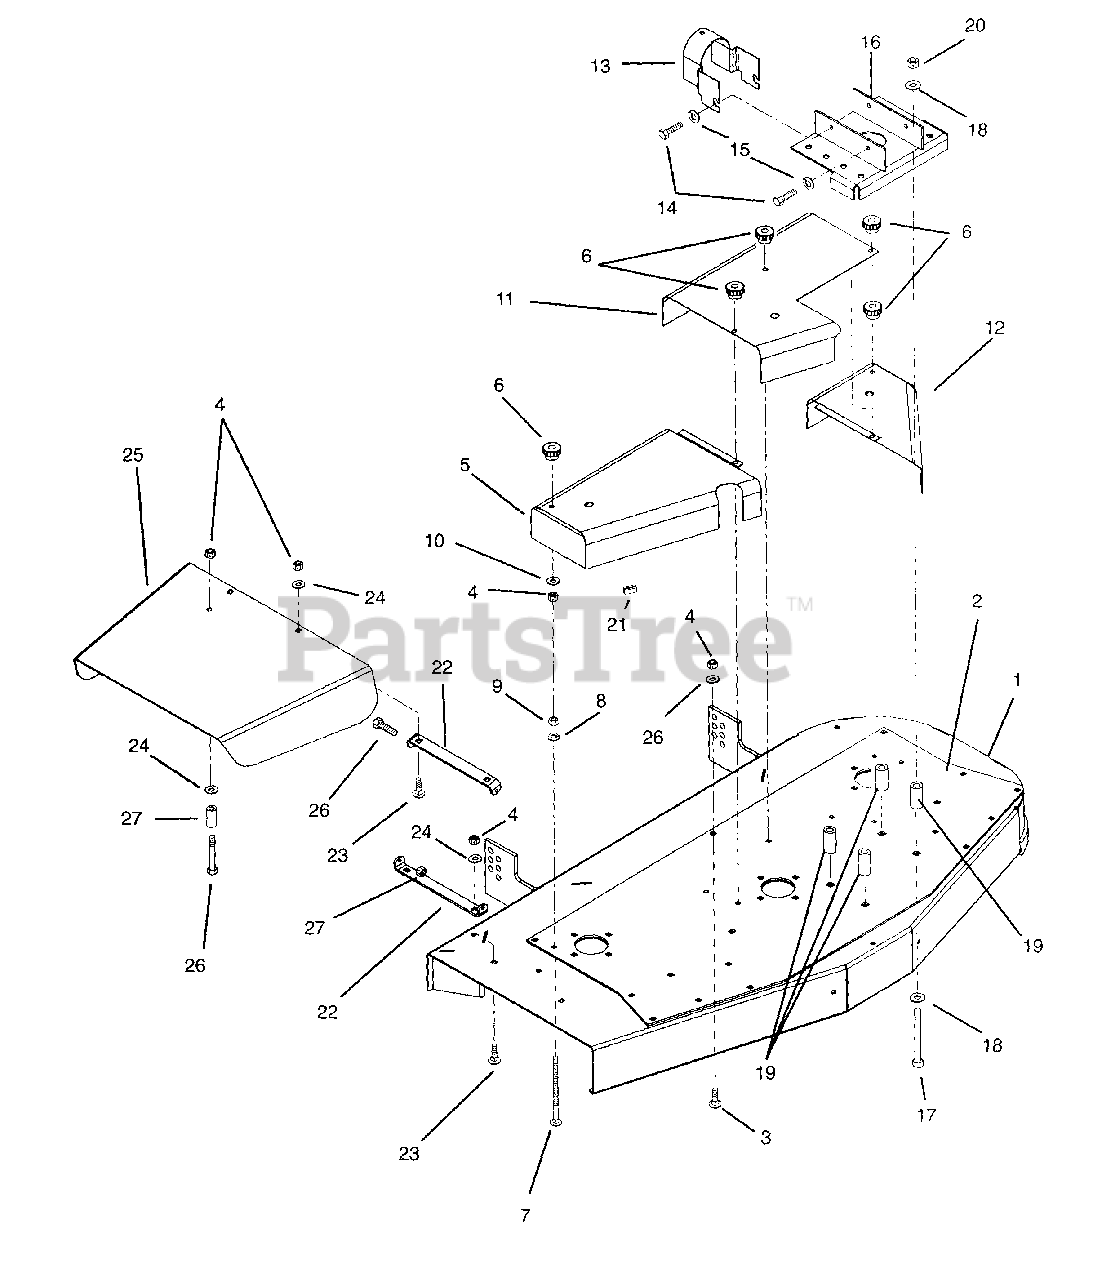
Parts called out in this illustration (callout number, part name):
1	Weldment, 50" Mower Deck
2	Plate, Reinforcing 50" Deck
3	Bolt-Round Head Square Neck .38-16 x .75 Grade 2
4	Nut-Locking-Center .38-16
5	Cover, Belt Right Hand 50"
6	Knob
7	Bolt-Round Head Square Neck .312-18 x 4.0
8	Washer-Locking .31 x .078
9	Nut-Hex .31-18
10	Washer-Flat-Steel .38 x .875 x .083
11	Cover, Belt Middle 50"
12	Cover, Belt Left Hand 50"
13	Shield, U-Joint
14	Bolt-Hex .38-16 x 1.00 Grade 5
15	Washer-Lock .38 x .094
16	Weldment, Gearbox
17	Bolt-Hex .50-13 x 3.50 Grade 5
18	Washer-Flat-Steel .531 x 1.06 x .095
19	Spacer .562 x 1.00 x 2.00
20	Nut-Locking-Center .50-13
21	Trim Bumper
22	Bracket, Chute
23	Bolt-Round Head Square Neck .38-16 x 1.00 Grade 2
24	Washer-Flat-Steel .406 x .812 x .065
25	Chute, Discharge 50"
26	Bolt-Hex .38-16 x 1.50 Grade 5
27	Bushing-Sleeve .407 x .625 x .750
